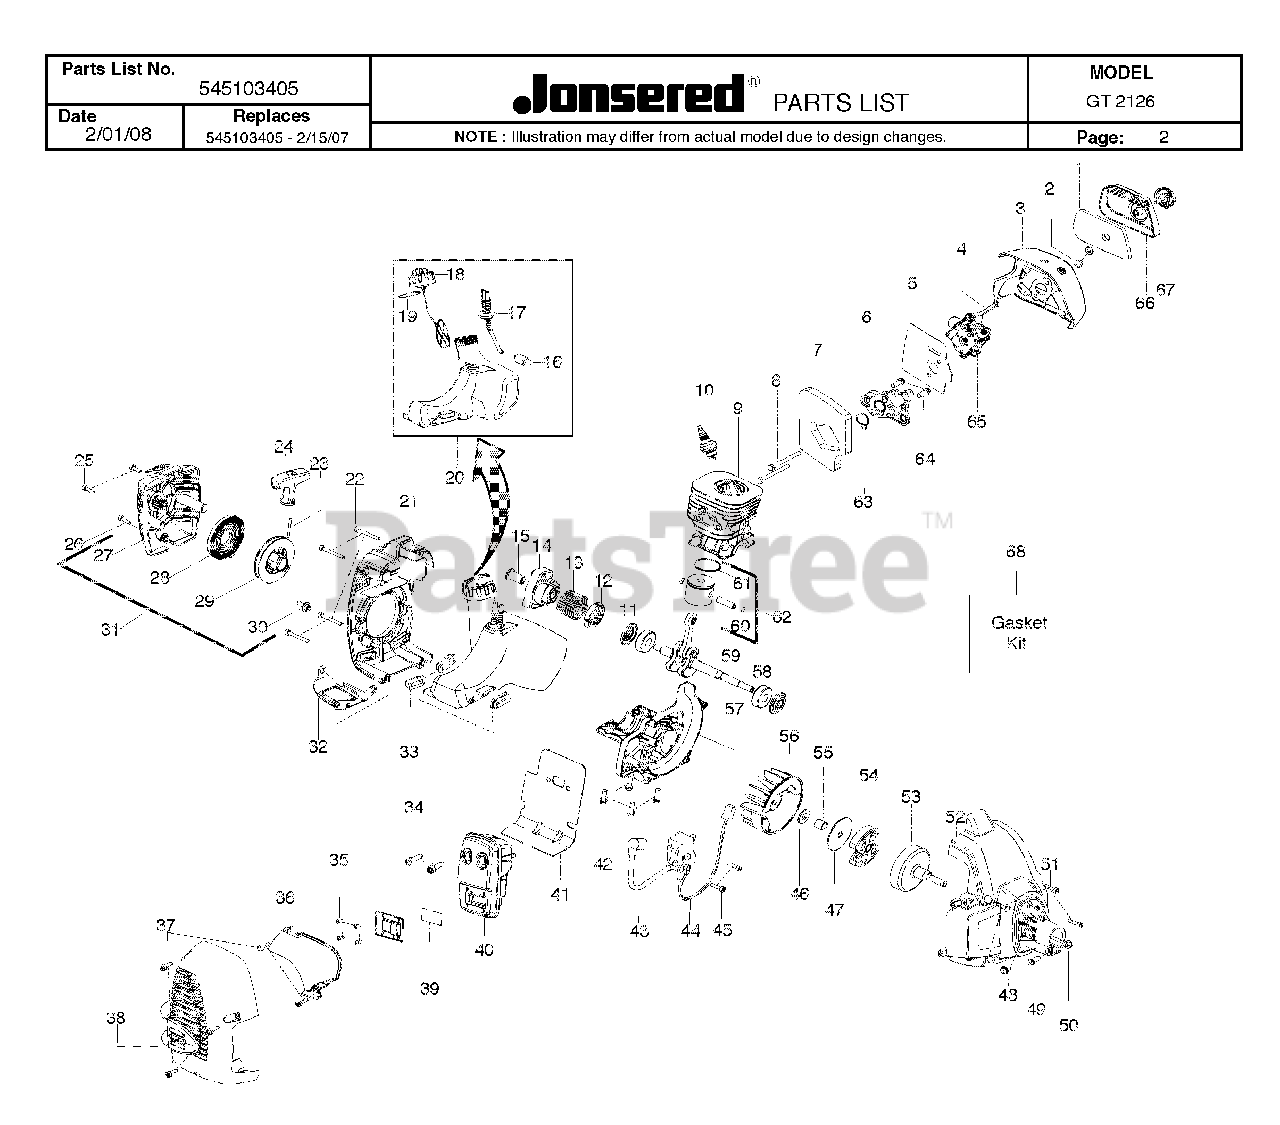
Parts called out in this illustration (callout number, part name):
1	FILTER AIRBOX
4	CHOKE LEVER
5	KIT GASKET CARB
6	CARB ADAPTOR
7	KIT GASKET 28CC TRIMMER
8	BOLT CARB ADAPTOR
9	CYLINDER
11	KIT SEAL CRANKSHAFT
12	WASHER STARTER
13	SPRING STARTER CUP
14	ASSY-STARTER CUP
15	COUPLING STARTER
16	FUEL PICK-UP ASSY
17	KIT FUEL LINE
18	ASSY - FUEL CAP W/RETAINER
19	O RING NITRILE
20	FUEL TANK ASSY
21	SHROUD REAR
25	SCREW M5-0.8X30MM
26	SCREW M4 X 1.75 PT 16MM
28	%KIT STARTER SPRING
29	KIT STARTER PULLEY
32	PLATE WEAR
33	ISOLATOR FUEL TANK
34	BOLT MUFFLER
35	SCREW-10-16 X 1/2 HI-LO
36	SHIELD HEAT
37	SCREW M4 X 1.75 PT 16MM
39	KIT SPARK ARRESTOR SCREEN
40	ASSY-MUFFLER
41	GASKET PAPER METAL
42	B0LT, C/SHAFT 36/41
43	IGNITION MODULE
44	ASSY MODULE LEAD WIRE
45	SCREW M4 X .70 TT 16MM
46	WASHER CLUTCH
47	WASHER-CLUTCH
50	LOCKNUT-HEX 10-24
51	SCREW M4 X .70 TT 16MM
54	%KIT CLUTCH ASSY
55	SPACER FLYWHEEL
57	CRANKCASE CASTING
58	BEARING RADIAL BALL (6201)
59	KIT CRANKSHAFT ASSY
60	WRIST PIN RET.
61	RING PISTON
62	KIT PISTON 28CC TRIMMER
63	KIT GASKET 28CC TRIMMER
64	B0LT, C/SHAFT 36/41
66	COVER AIR BOX
67	ASSY - AIR BOX KNOB
68	KIT GASKET 28CC TRIMMER
